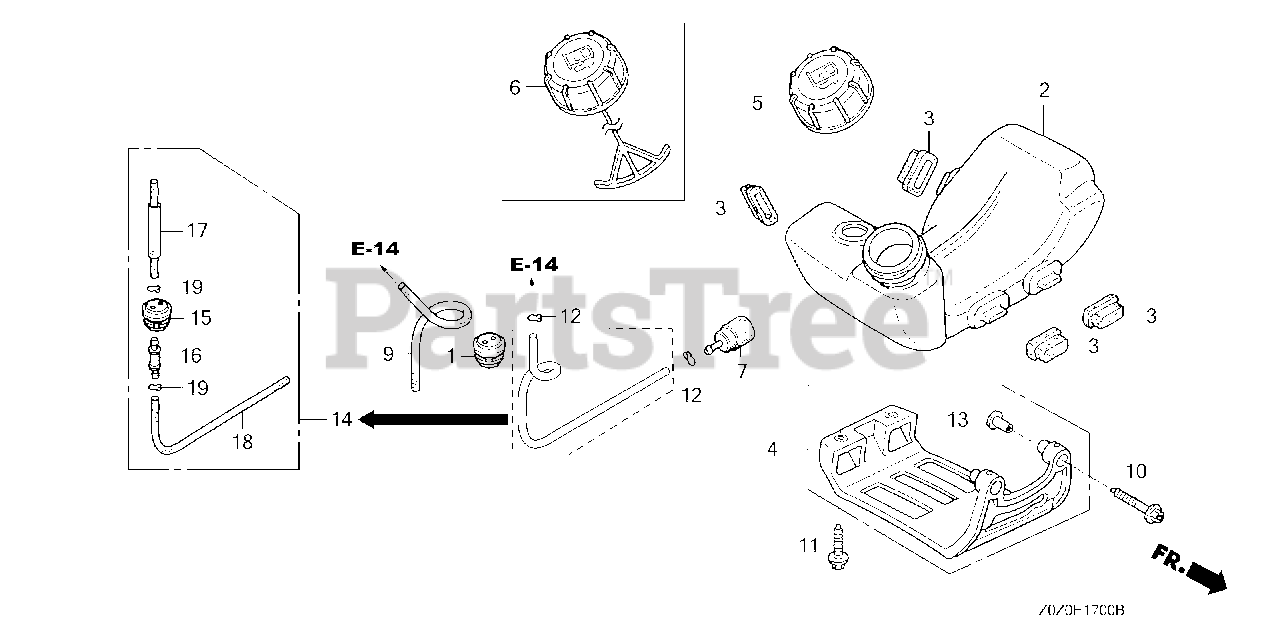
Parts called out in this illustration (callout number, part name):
1	GROMMET, FUEL TUBE
2	TANK, FUEL
2	TANK, FUEL (COO)
3	RUBBER, TANK MOUNTING
5	CAP ASSY., FUEL TANK
7	FILTER, FUEL
8	TUBE, FUEL TANK
9	TUBE, FUEL RETURN
12	CLIP, TUBE
14	GROMMET ASSY., FUEL TANK
15	GROMMET, FUEL TUBE
16	FITTING
17	TUBE, FUEL FEED
18	TUBE A, FUEL
19	CLIP, TUBE
